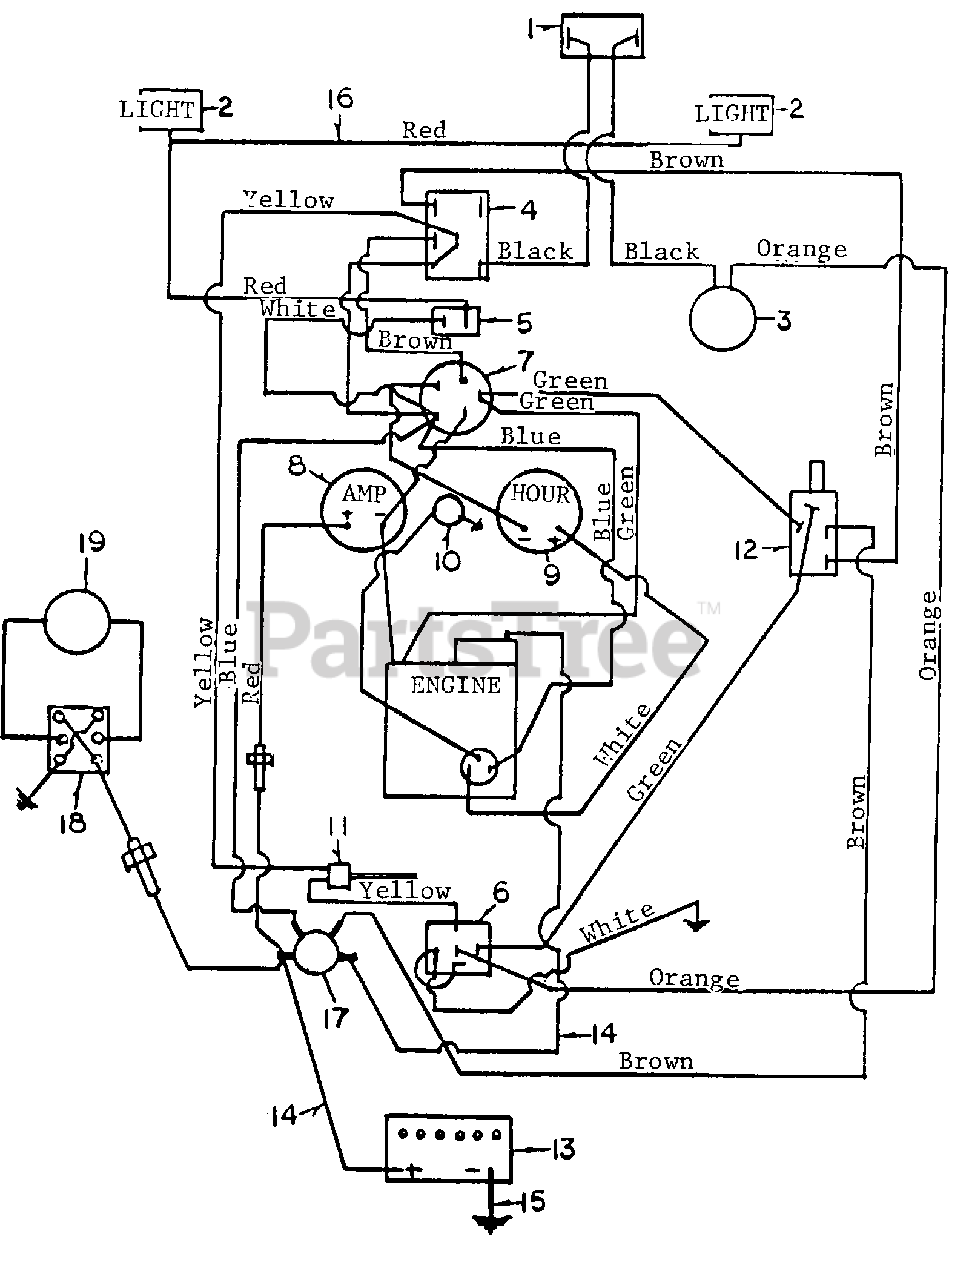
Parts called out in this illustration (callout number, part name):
1	Amp Circuit Breaker
2	Headlight Assembly
3	Electric Clutch Assembly
4	PTO Clutch Switch
5	Light Switch
6	Relay
7	Ignition Switch
13	Battery
16	Light to Switch Wire
18	3 Position Deck Lift Switch
19	Electric Lift Actuator
